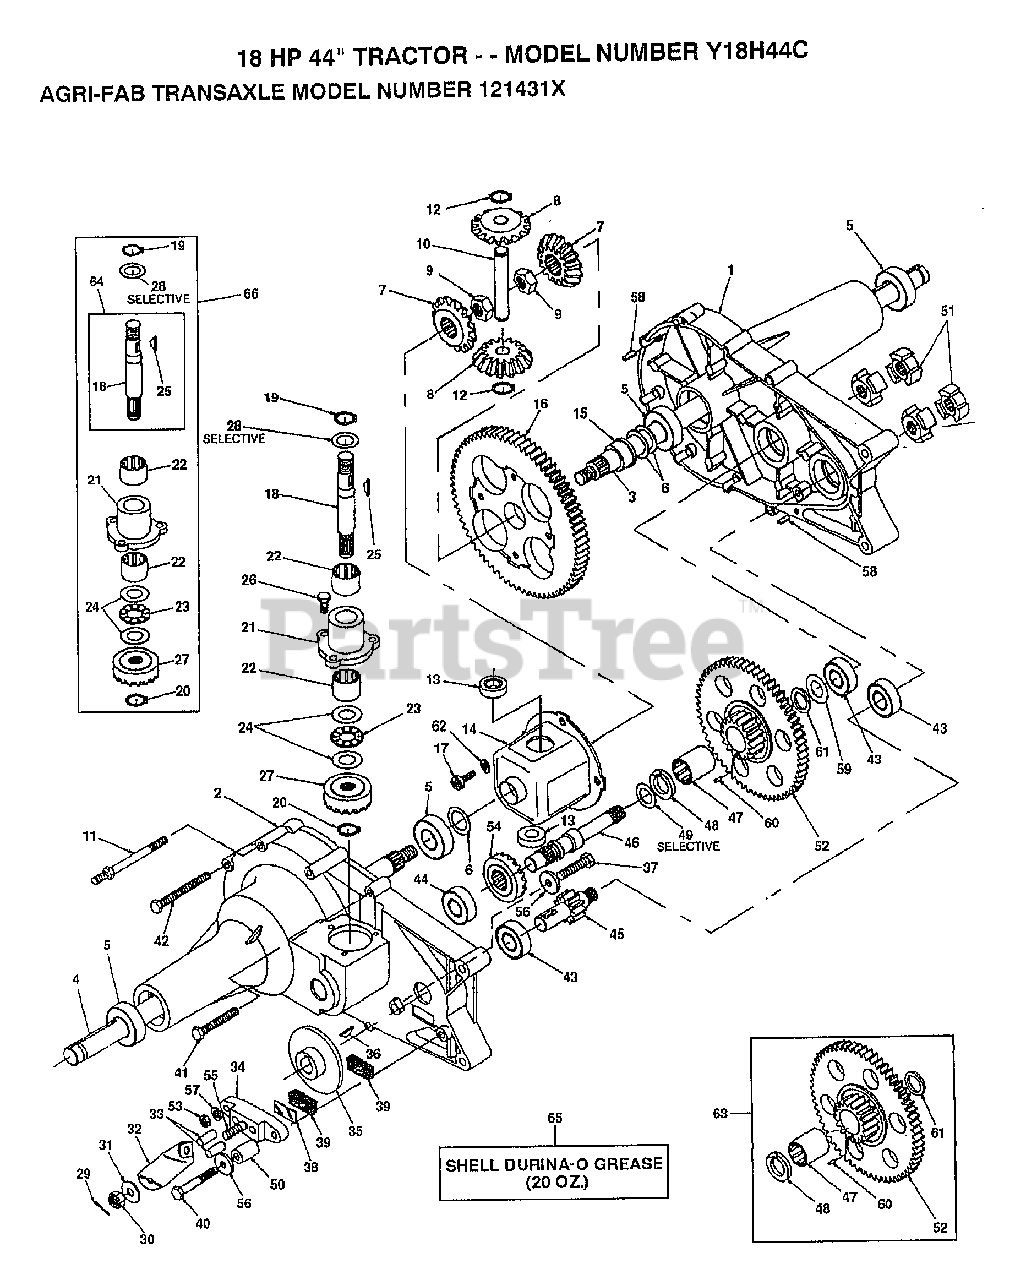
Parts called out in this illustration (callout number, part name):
1	HSG HALF LH-44077
2	HSG HALF RH-44076
3	AXLE LH -44273
4	AXLE RH-44272
5	BEARING.44121.AGR
6	WASHER -44008
7	GEAR MITER -44096
8	GEAR MITER -44097
9	NUT -44133
10	SHAFT CROSS
11	SCREW-STUD -44271
12	SNAP RING -44146
13	"THRUST, BEARING -44128"
14	HOUSING.ASM.DIFF.-62590
15	"FLANGE, BEARING-44129"
16	GEAR
17	BOLT -44126
18	SHAFT INPUT-44270
19	SNAP RING -44145
20	RET RING (44144)
22	"NEEDLE, BEARING 44099"
23	BEARING.NEE.44139
24	WASHER-44109
25	KEY.44136.HYDRO
26	SCREW
28	WASHER -44371
29	PIN COTTER -44101
30	WASHER -44150
31	WASHER FLAT -44130
32	ARM BRAKE 23710
33	PIN BRAKE ACTUATO -44127
34	BRAKE YOKE
35	DISC BRAKE -(44090)
36	KEY -44143
37	SCREW -44277
38	PLATE PUCK -44134
40	SCREW -44300
41	SCREW -44123
42	SCREW -44124
44	"BALL, BEARING -44232"
45	SHAFT PINION 44083
46	SHAFT DRIVE-44080
47	NEEDLE BEARING -44342
48	THRUST.BRONZE -44343
49	WASHER -44371
50	SPACER -23711
51	COUPLING- 44084
52	GEAR.60/17.44523
53	NUT -43178
54	PINION-DR.44079
55	BOLT SQ HD
56	WASHER -44278
57	WASHER -44137
58	PIN ROLL-44269
59	WASHER -44125
60	DOWEL PIN -44346
61	SEAL GREASE -44394
62	WASHER.43177.AGRI
63	ASS'Y GEAR REDUCT
65	GREASE.50416.10OZ
66	"KIT, SHAFT 62636"
